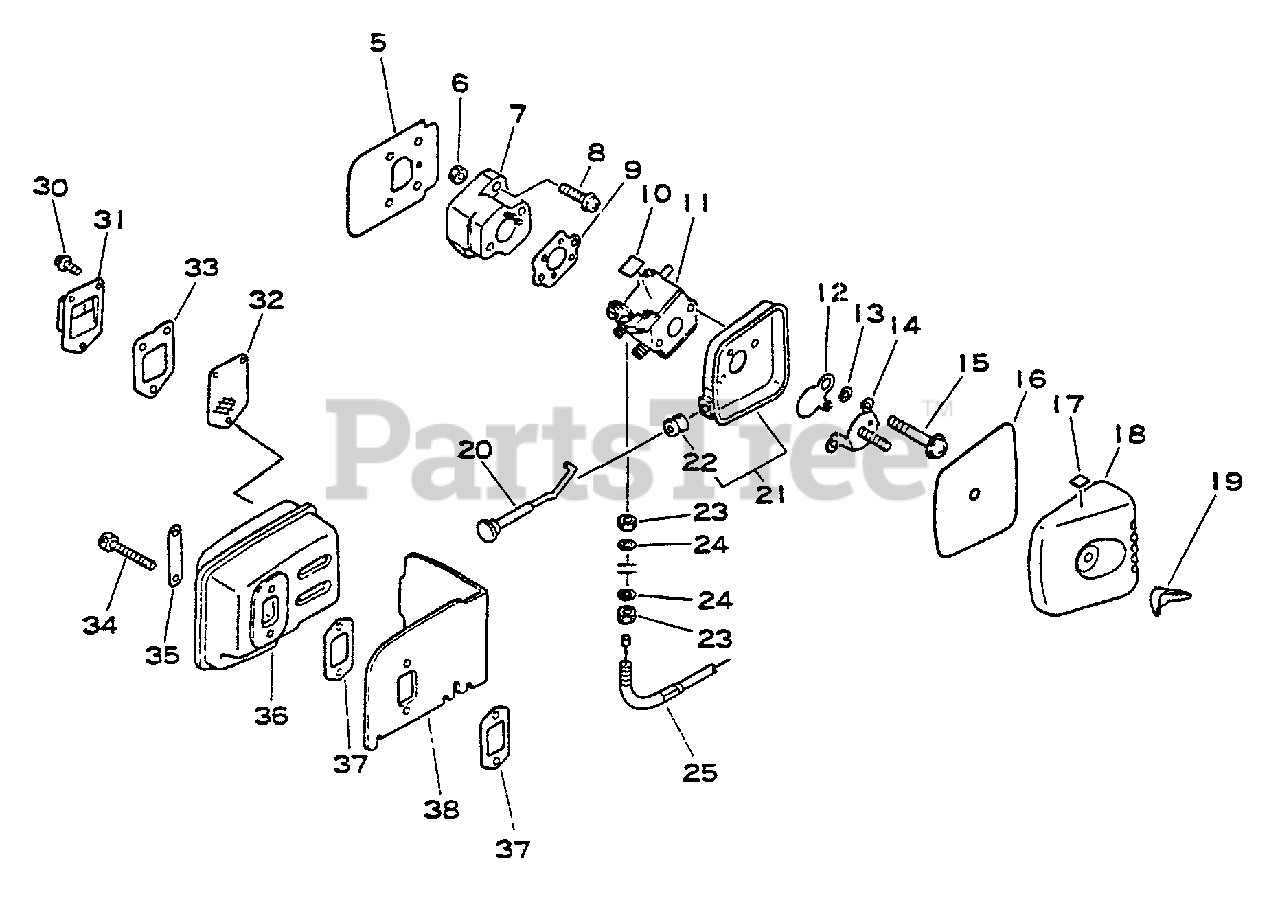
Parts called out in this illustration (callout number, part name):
5	SHIELD, INTAKE
7	INSULATOR, INTAKE
8	SCREW - 5X20
9	GASKET, INTAKE
10	LABEL - CAUTION
11	CARBURETOR
12	SHUTTER, CHOKE
13	WASHER - 5
14	PLATE, PREVENT
15	SCREW - 5X57
16	FILTER, AIR
17	LABEL - CHOKE
18	COVER, AIR FILTER
19	WINGNUT - 6
20	ROD, CHOKE
21	CASE, AIR FILTER
24	WASHER - 6
25	CABLE, THROTTLE
30	SCREW - 4X10
31	GUIDE, EXHAUST
32	SCREEN, SPARK ARRESTOR
33	GASKET, EXHAUST
34	SCREW - 5X55
37	GASKET, EXHAUST
38	COVER, MUFFLER
